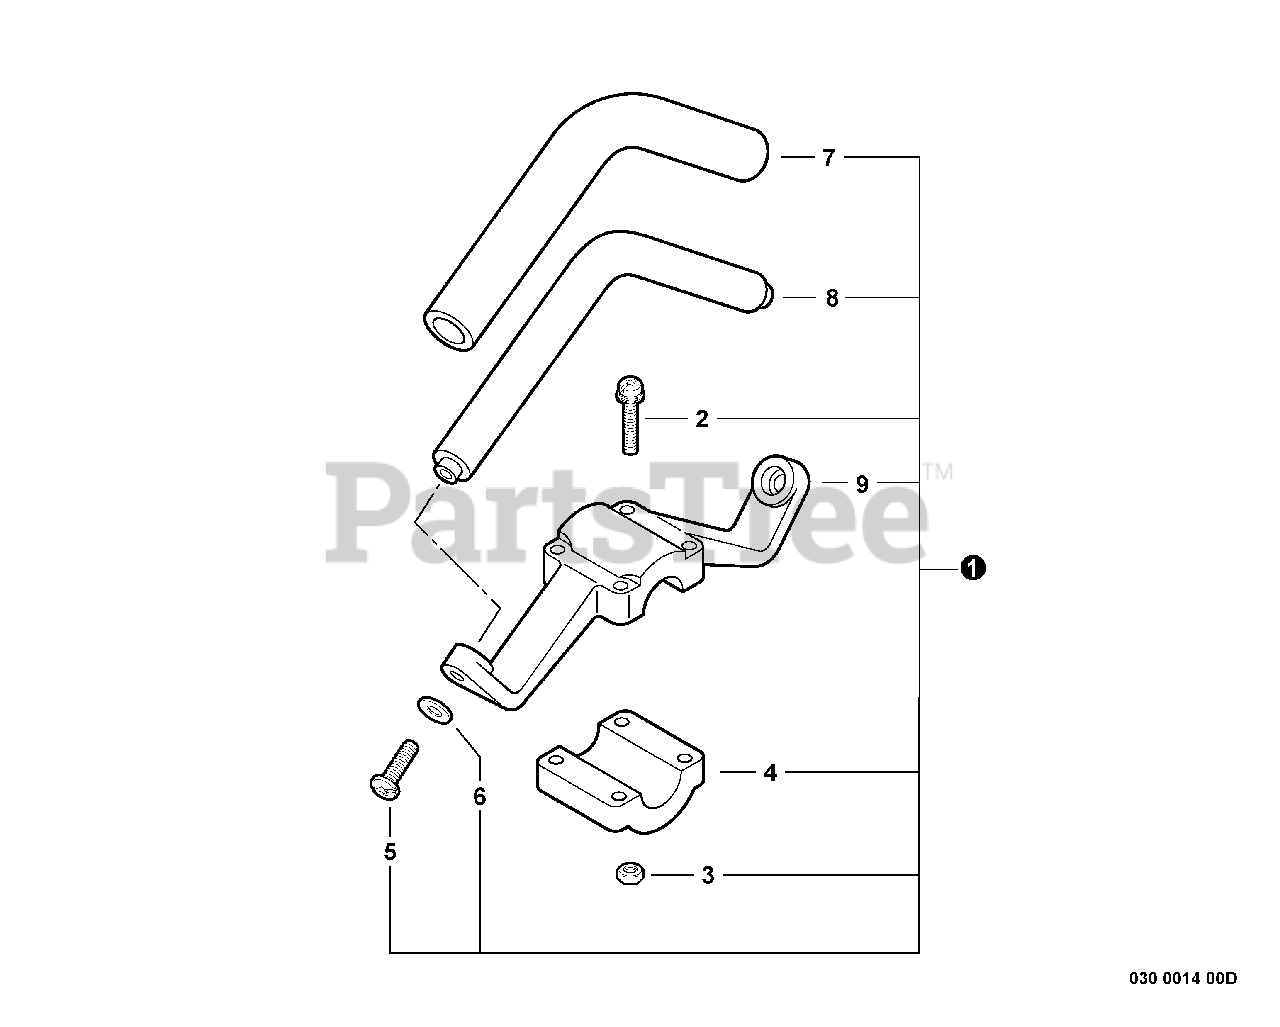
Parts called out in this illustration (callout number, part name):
1	HANDLE ASSY - FRONT
2	SCREW - 5X35
4	BRACKET, HANDLE - LOWER
5	SCREW - 5X20 -- TAPPING
6	WASHER - 5
7	GRIP, HANDLE
8	HANDLE - FRONT
9	BRACKET, HANDLE - UPPER
